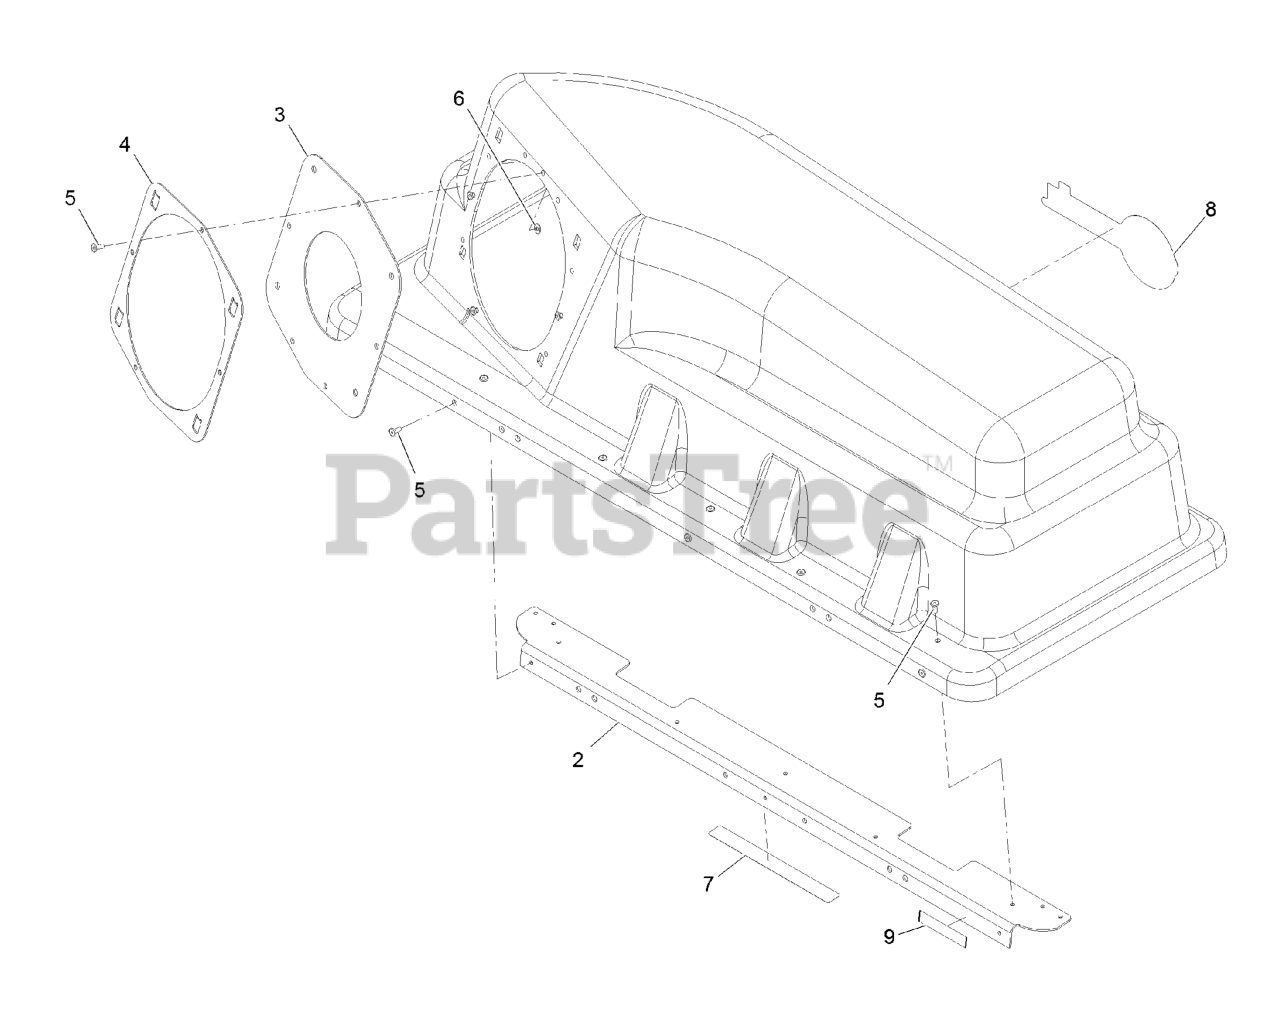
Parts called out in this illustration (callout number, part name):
2	STIFFENER-BAGGER, TOP
4	RING-RETAINER
5	RIVET-BLIND
6	WASHER-FLAT
7	DECAL-CRUSH HAZARD BAGGER
8	DECAL-EXMARK LOGO
9	DECAL-WARNING
